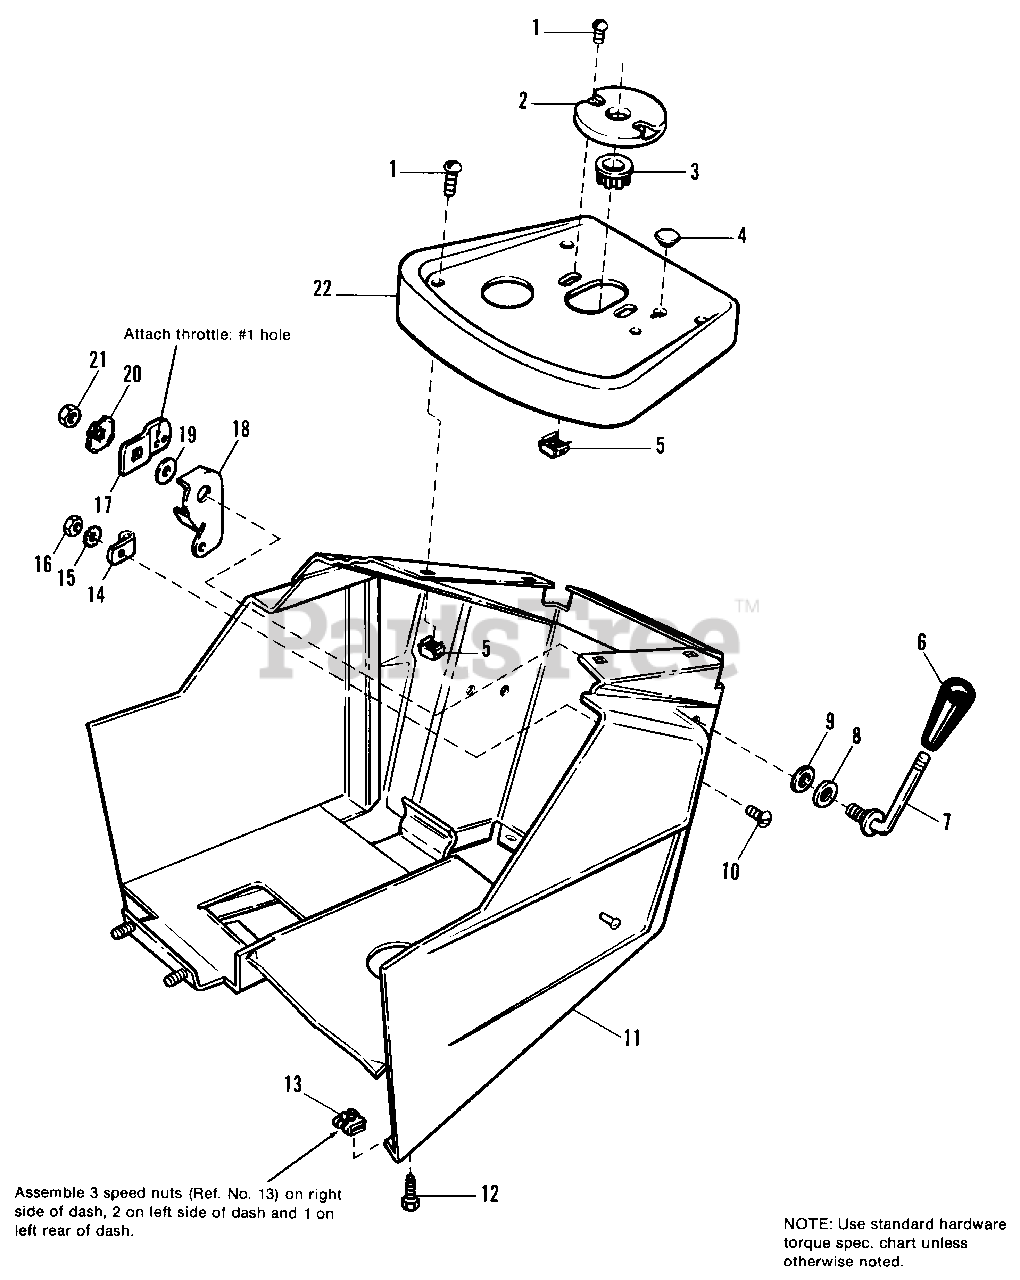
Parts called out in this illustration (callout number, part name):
1	SCREW, Machine, Rd. Hd., 1/4-20 x 12
2	PLATE, Adjusting, Steering
4	PLUG, Button
5	NUT, Tinnerman
6	KNOB
7	HANDLE, Clutch Control
10	SCREW, Round Hd., #10-32 x 1/2
11	DASH ASSY.
12	SCREW, Hex, Self Tapping, #14AB x 3/4
13	NUT, Speed
14	CLIP, Bowden Wire
15	LOCKWASHER, Ext. #10
16	NUT, Machine, Hex, #10-32
17	ARM, Throttle
18	STOP, Throttle
20	LOCKWASHER, Dished Type, 3/8
21	LOCKNUT, Hex, 3/8-16
22	PANEL, Instrument
